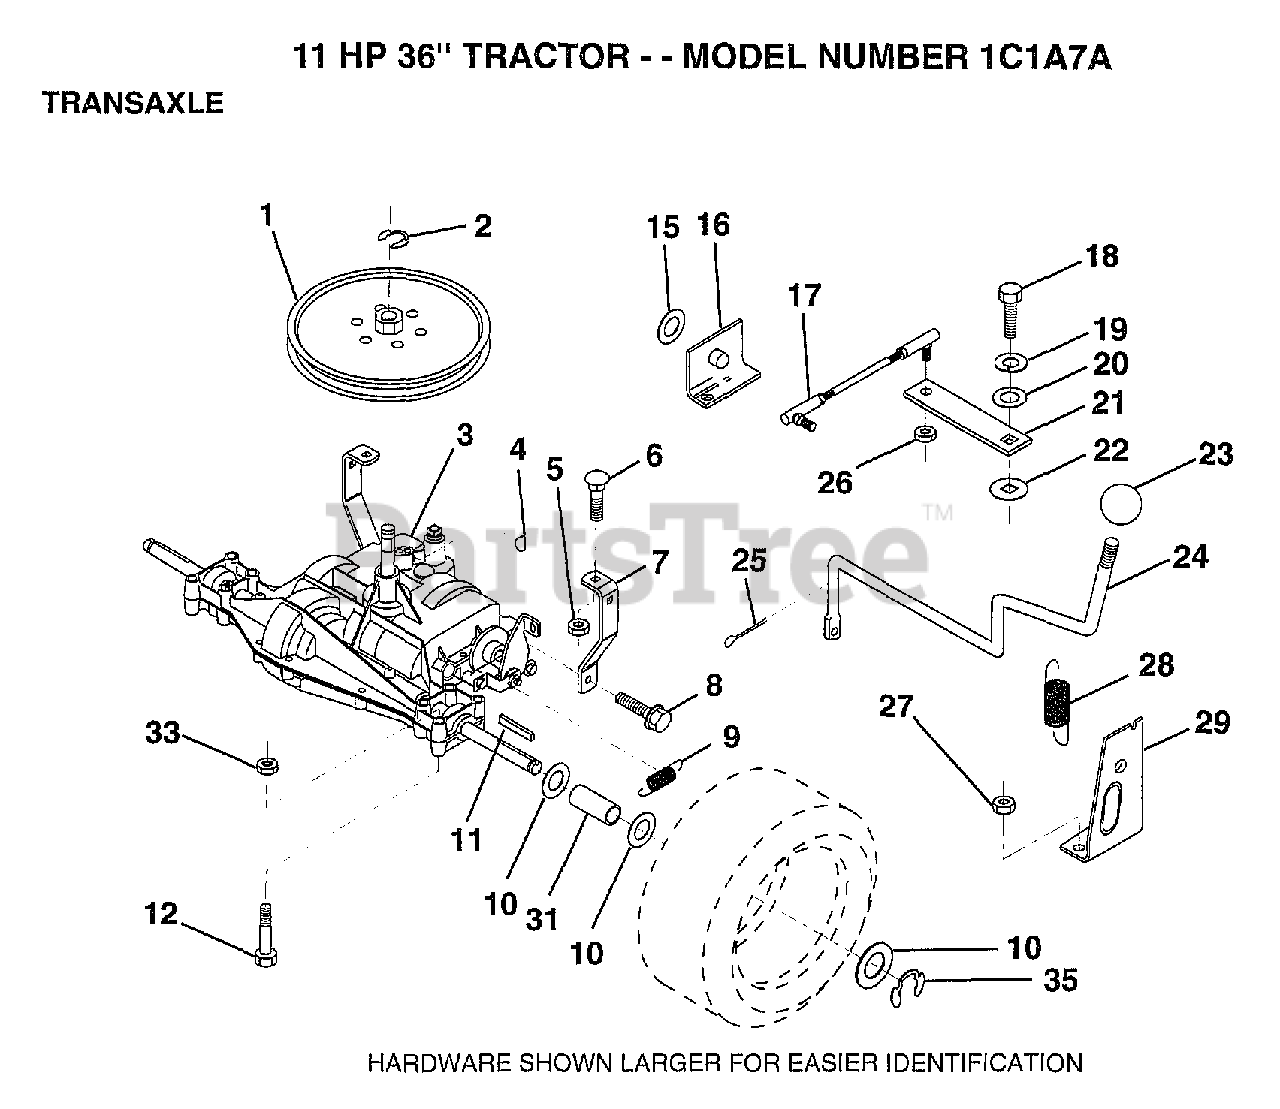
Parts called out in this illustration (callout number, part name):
1	PULLEY
5	NUT
6	BOLT
7	"STRAP,TORQUE"
8	SCREW
10	WASHER
11	SQUARE KEY
12	BOLT
16	"SUPT,HDLE SHT LH"
17	"LINK,SHIFT"
19	LOCKWASHER
20	WASHER LT
21	ARM SHIFT
22	WASH-SHFT PLT LT
23	KNOB T (1/2-HOLE)
24	"ROD,SHIFT"
25	PIN COTTER 1/8
26	NUT.LOCK.5/16-24
28	"SPRING,EXT"
29	"SUPT,HDLE RH"
31	SPACER LT
33	NUT
35	E-RING LT
